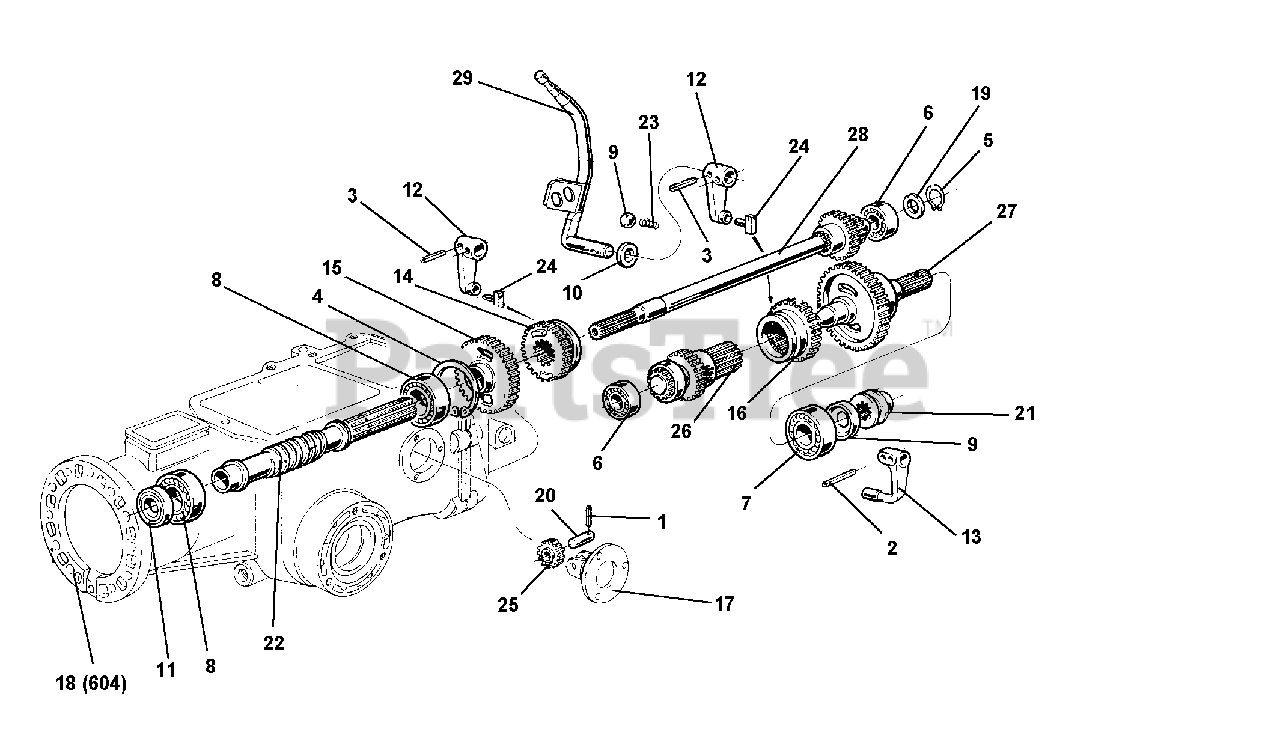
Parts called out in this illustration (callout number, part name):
1	PIN, LOCKING 2.5 X 22 DIN 1481
2	LOCKING PIN 4 X 20 SPIRAL
3	LOCKING PIN 4 X 24 SPIRAL
4	CIRCLIP, INTERN D 52
6	BEARING 15 X 35 X 11 6202
7	BEARING 20 X 47 X 14 6204
8	BEARING 25 X 52 X 15 6205
9	BALL 15/32 RIV RB-11.906
10	SEAL, OIL 12 X 19 X 5 STANDARD
11	SEAL, OIL 15 X 40 X 10 STANDARD
12	LEVER, SPEED CHG SLDG GR
13	SLIDE LEVER
14	SLIDER SPEEDS
15	WHEELS FIRST SPEED
16	SLIDER, REDUCTION UNIT
17	FLANGE, REVERSE SPEED
18	CASING 5 SPEEDS GEARBOX
19	WASHER 15.1 X 25 X 2
25	REVERSE SPEED GEAR
26	GEAR TRIPLE
27	P.T.O. SHAFT
28	CLUTCH SHAFT F. MOTOR MOWER
29	SHIFT LEVER
